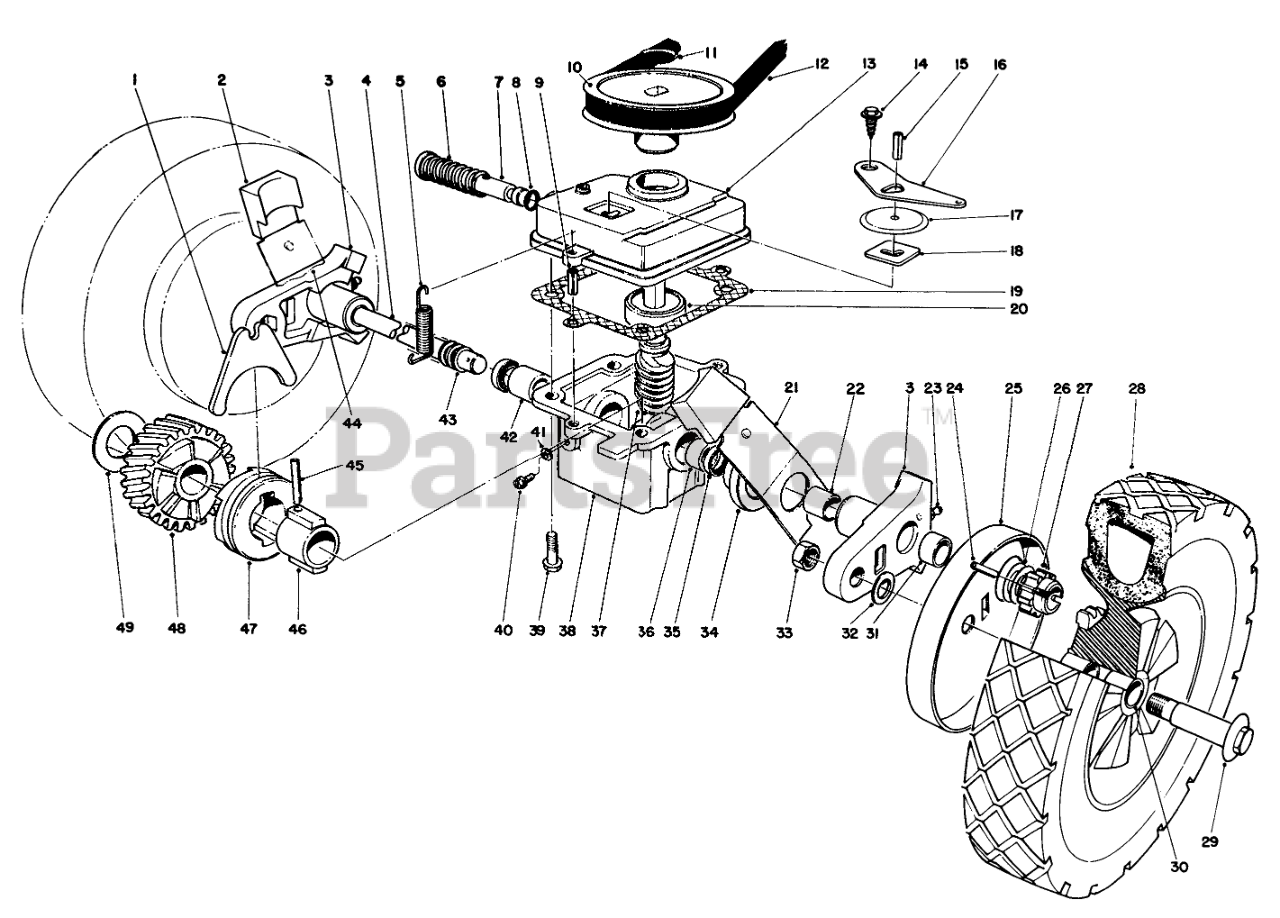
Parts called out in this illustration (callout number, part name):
1	SHIFTER FORK
2	KNOB-ARM
3	Pivot Arm (Incl. Ref. #22, 23&31)
4	DRIVE SHAFT (SERVCE)
5	TENSION SPRING
6	SPRING
7	SHIFTER ROD
8	O-RING
9	3/16 X 1/2 ROLL PIN
10	PULLEY
11	PUSH-ON 93-3236
12	V BELT
13	Case-Upper
14	Screw
15	PIN-ROLL
16	SHIFTER ARM
17	TRANS DUST COVER
18	LATCH PLATE
19	GASKET
20	BEARING
21	SPRING ARM ASM SP LH
22	BUSHING
23	FITTING-GREASE
24	Pin
25	WHEEL COVER
26	THRUST WASHER
27	PINION GEAR 14T
28	Wheel, Tire & Gear Assembly (Incl. Ref. #30)
29	WHEEL BOLT
30	BUSHING
31	BUSHING
32	WASHER
33	NUT-LOCK
34	CAP-END
35	SEAL-OIL
36	BUSHING
37	Worm Shaft & Gear (Incl. Ref. #48)
38	Gear Case (Incl. Ref. #35-36 & 42)
39	Screw
40	NYLON SCREW
41	FILL PLUG GASKET
42	BUSHING
43	COVER-SHAFT, DRIVE
44	SPRING ARM ASM SP RH
45	COIL PIN
46	SLEEVE
47	CLUTCH JAW
48	Helical Gear
49	THRUST WASHER
